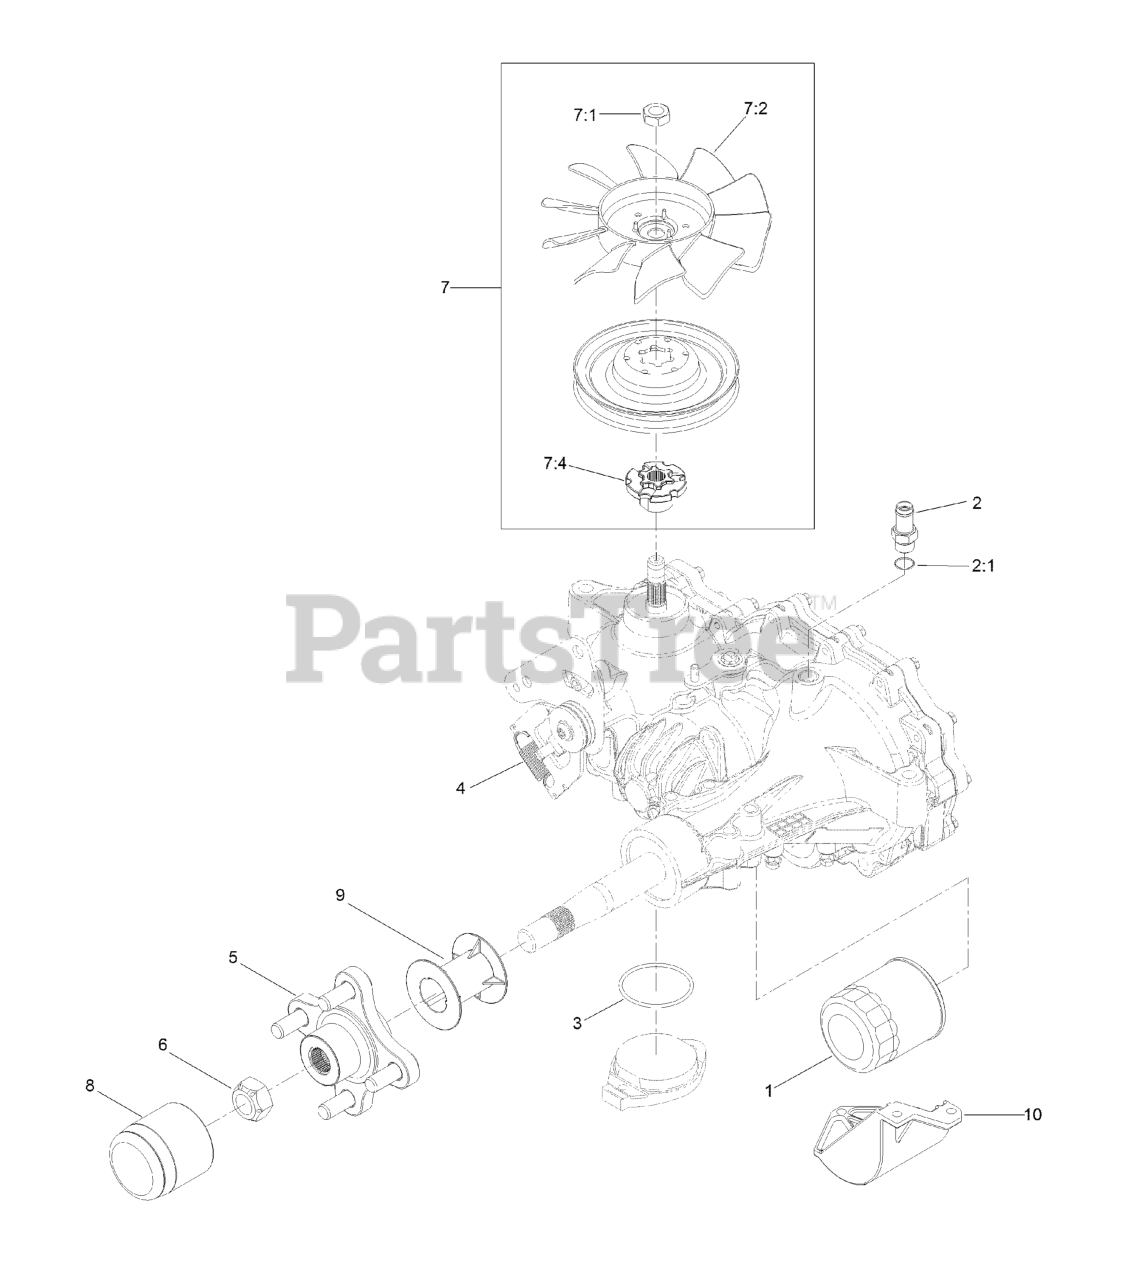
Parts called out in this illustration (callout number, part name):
1	ELEMENT-OIL FILTER, HYD
2	ADAPTER-STRAIGHT
2:1	O-RING
3	O RING-SEAL
4	SPRING-EXTENSION
5	HUB-OFFSET
6	NUT-HUB
7	FAN AND PULLEY KIT
7:4	HUB-PULLEY
8	CAP-AXLE, LONG
9	TUBE-AXLE
10	GUARD-FILTER, LH
99	BRAKE SHAFT SEAL KIT
